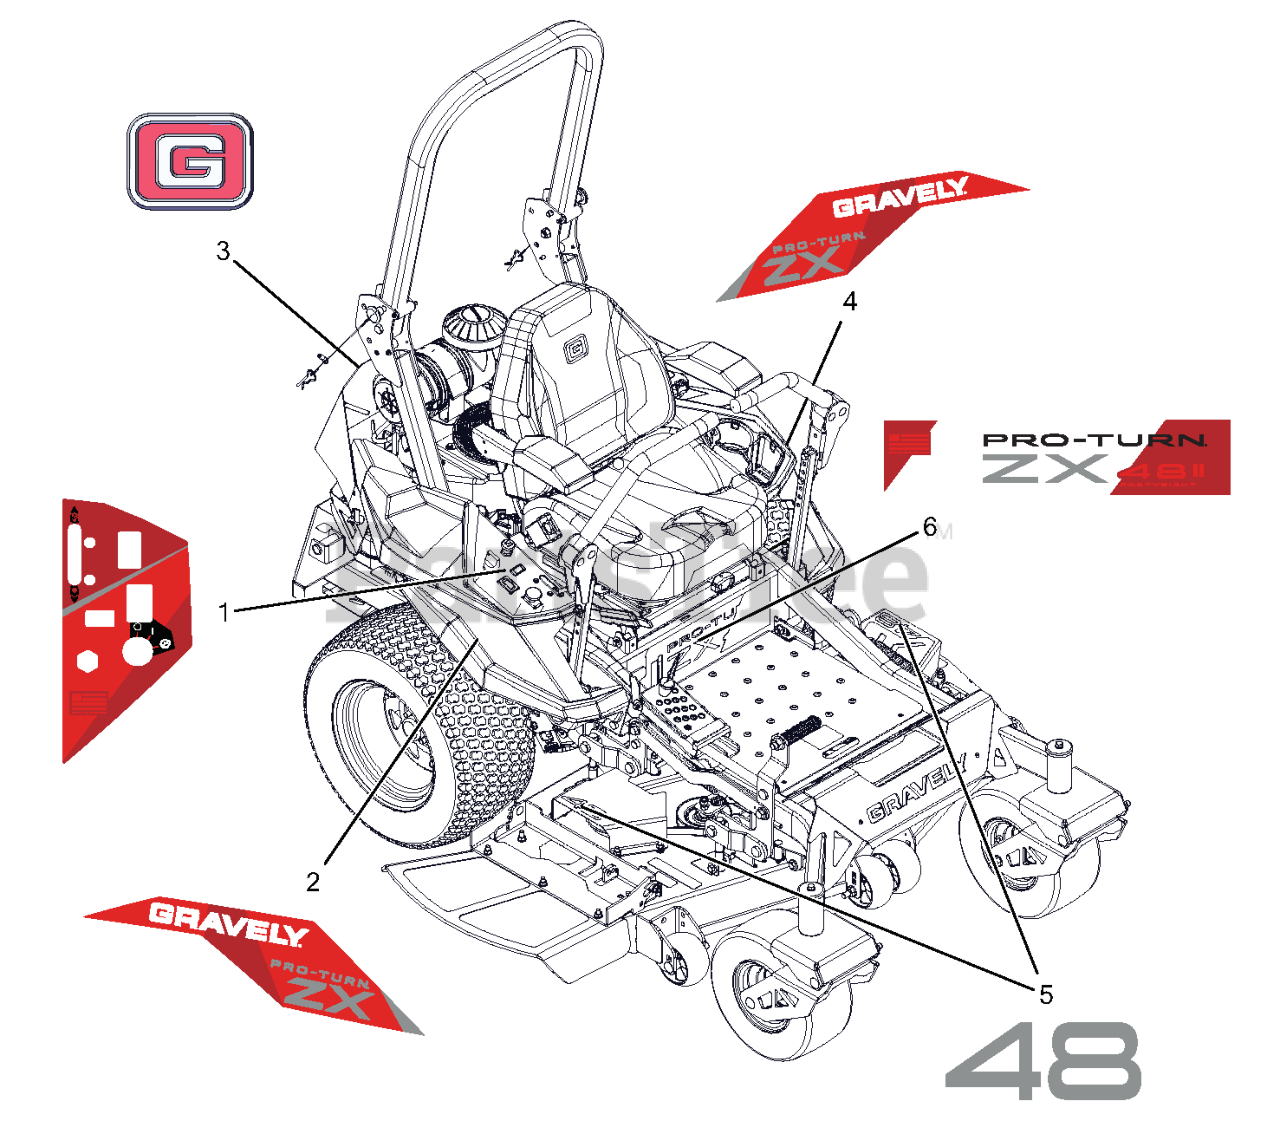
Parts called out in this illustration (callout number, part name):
1	DECAL, CONTROL PANEL
2	DECAL, FENDER RH - PTZX
3	DECAL, GRAVELY BRAND
4	DECAL, FENDER LH - PTZX
5	DECAL, DECK - 48
6	DECAL, PTZX -48
